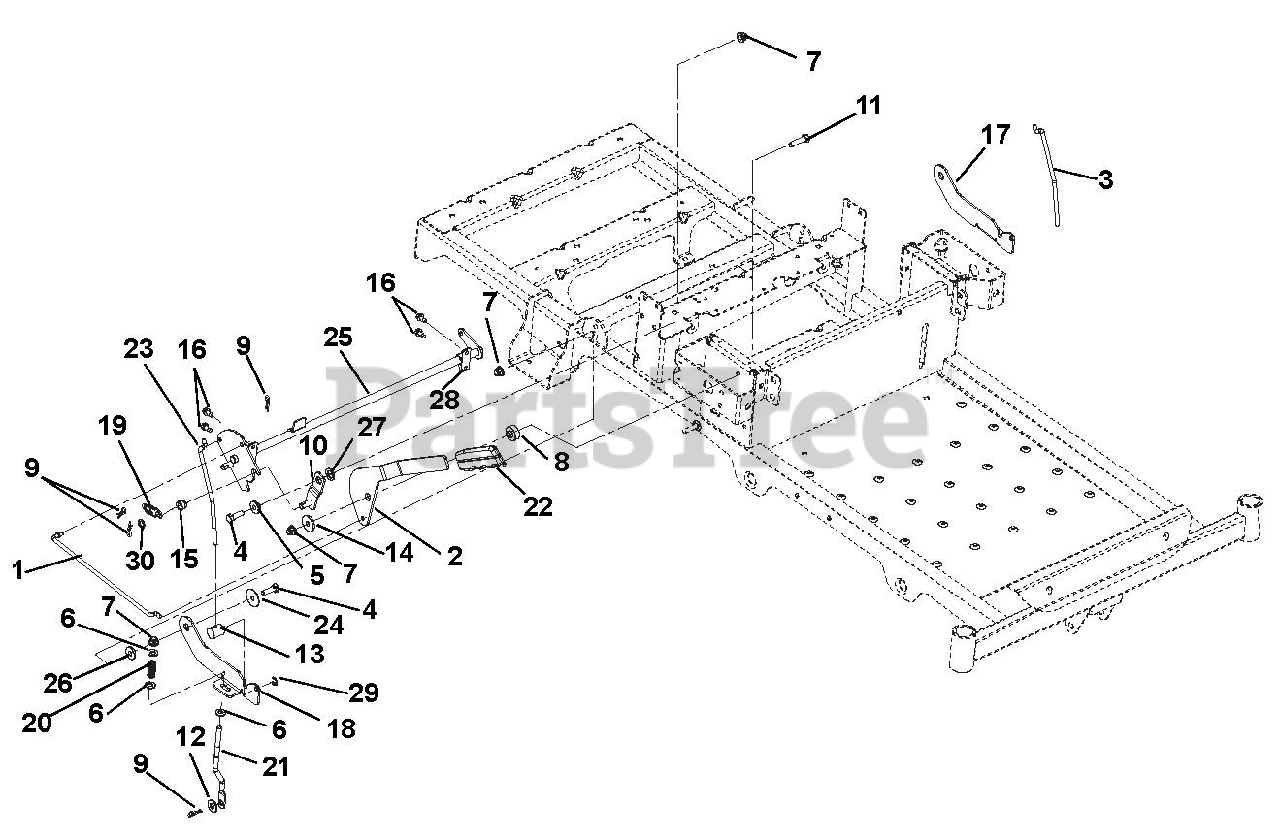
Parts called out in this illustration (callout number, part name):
1	LINK, BRAKE HANDLE
2	HANDLE, PARKING BRAKE
3	LINK, NEUTRAL LH
4	@BLT-HEX .31-18X1.00 GR5 YWZC
5	BSHG-FLG .32X.500X.344X.880
6	@WSHR-FL-STL.344X.688X.065YWZC
7	@NUT-LK-NYL-FLG .31-18 YWZC
8	SPCR,BRAKE .32X.49X.192X1.00
9	PIN-HAIR INT .08X.18X1.18 YWZC
10	WELDMENT,DETENT ARM
11	@BLT-HEX .31-18X1.25 GR5 YWZC
12	@WSHR-FL-STL.38X.875X.083 YWZC
13	TRUNION, 1/4-20
14	WSHR-FL-STL .344X1.125X.135
16	SCR-TAP .25-20X.50 HWH TR YWZ
17	LATCH, LH NEUTRAL
18	LATCH, RH NEUTRAL
19	SG-TENS .072X.565X1.87
20	SPRING, COMPRESSION
21	LINK, BRAKE COG
22	GRIP, PARKING BRAKE (YELLOW)
23	LINK, NEUTRAL RH
24	WSHR-FL-STL .347X1.254X.048YWZ
25	WLDMT, BRAKE SHAFT
26	BSHG, FLG .325X.499X.26X.88
27	WSHR-FL-STL .52X.827X.062 YWZC
28	BUSHING-.50 CLAMP BLOCK MOLDED
29	RG-RTNG-EXT .250X.025
30	WSHR,.385X.745X.030 STL YWZC
